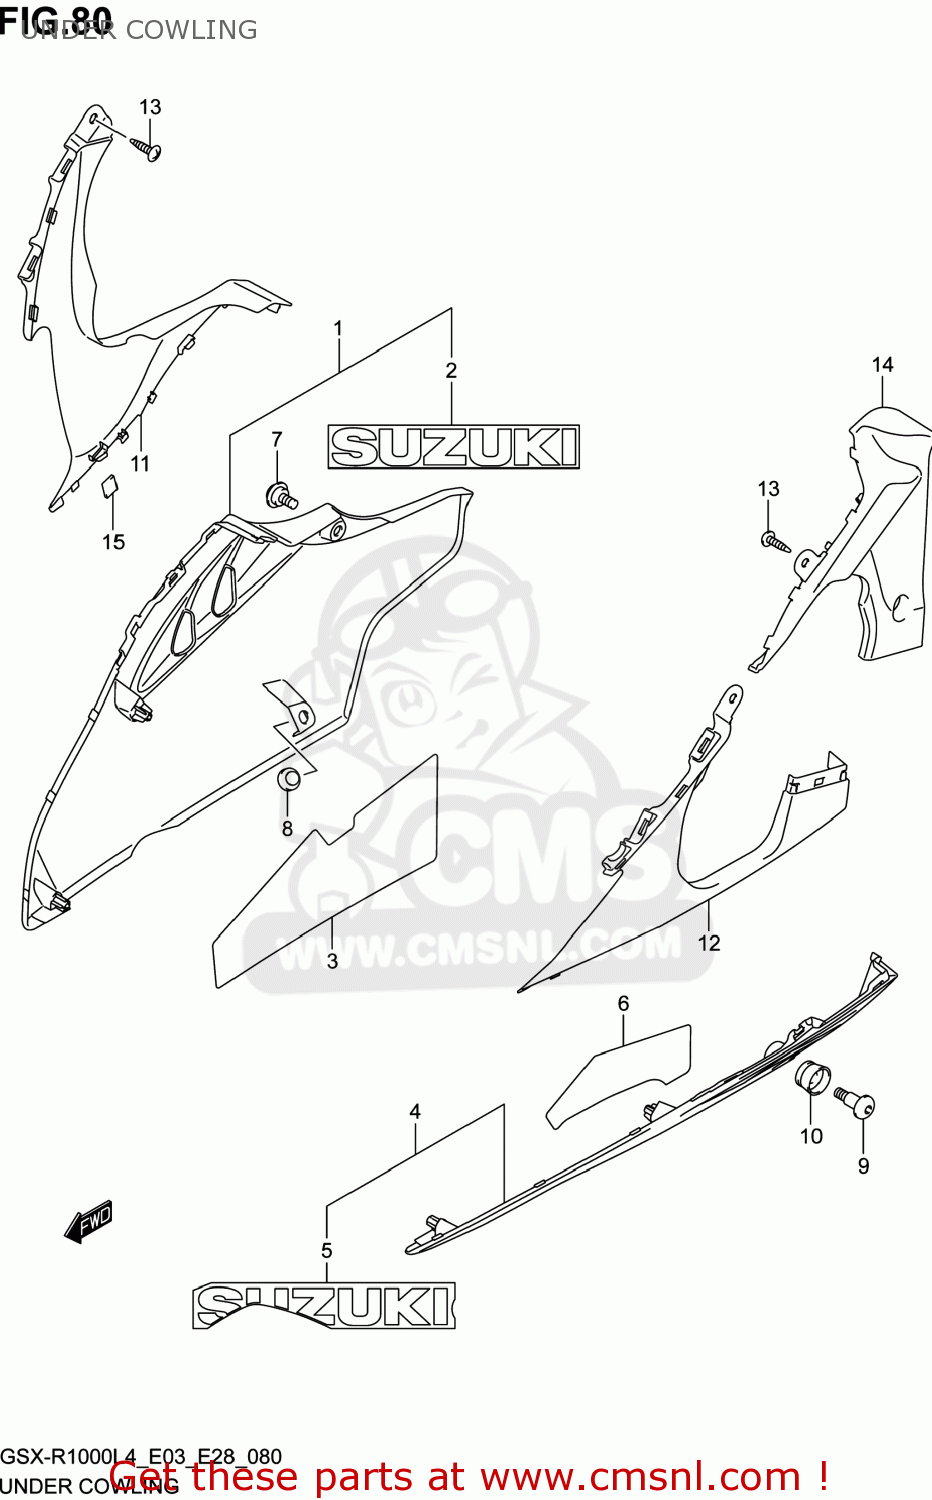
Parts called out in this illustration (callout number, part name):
1	COWLING,UNDER,R(GRAY)
2	EMBLEM,SUZUKI
3	SHIELD,UNDER COWL HEAT,R
4	COWLING,UNDER,L(GRAY)
5	EMBLEM,SUZUKI,L
6	SHIELD,UNDER COWL HEAT,L
7	SCREW,UNDER COWL,R
8	CUSHION
9	BOLT(6X20)
10	CUSHION,UNDER COWLING,L
11	COWLING,SIDE LWR,R
12	COWLING,SIDE LWR,L
13	SCREW
14	COVER,SIDE COWL,L
15	CUSHION,RR COVER NO.2
